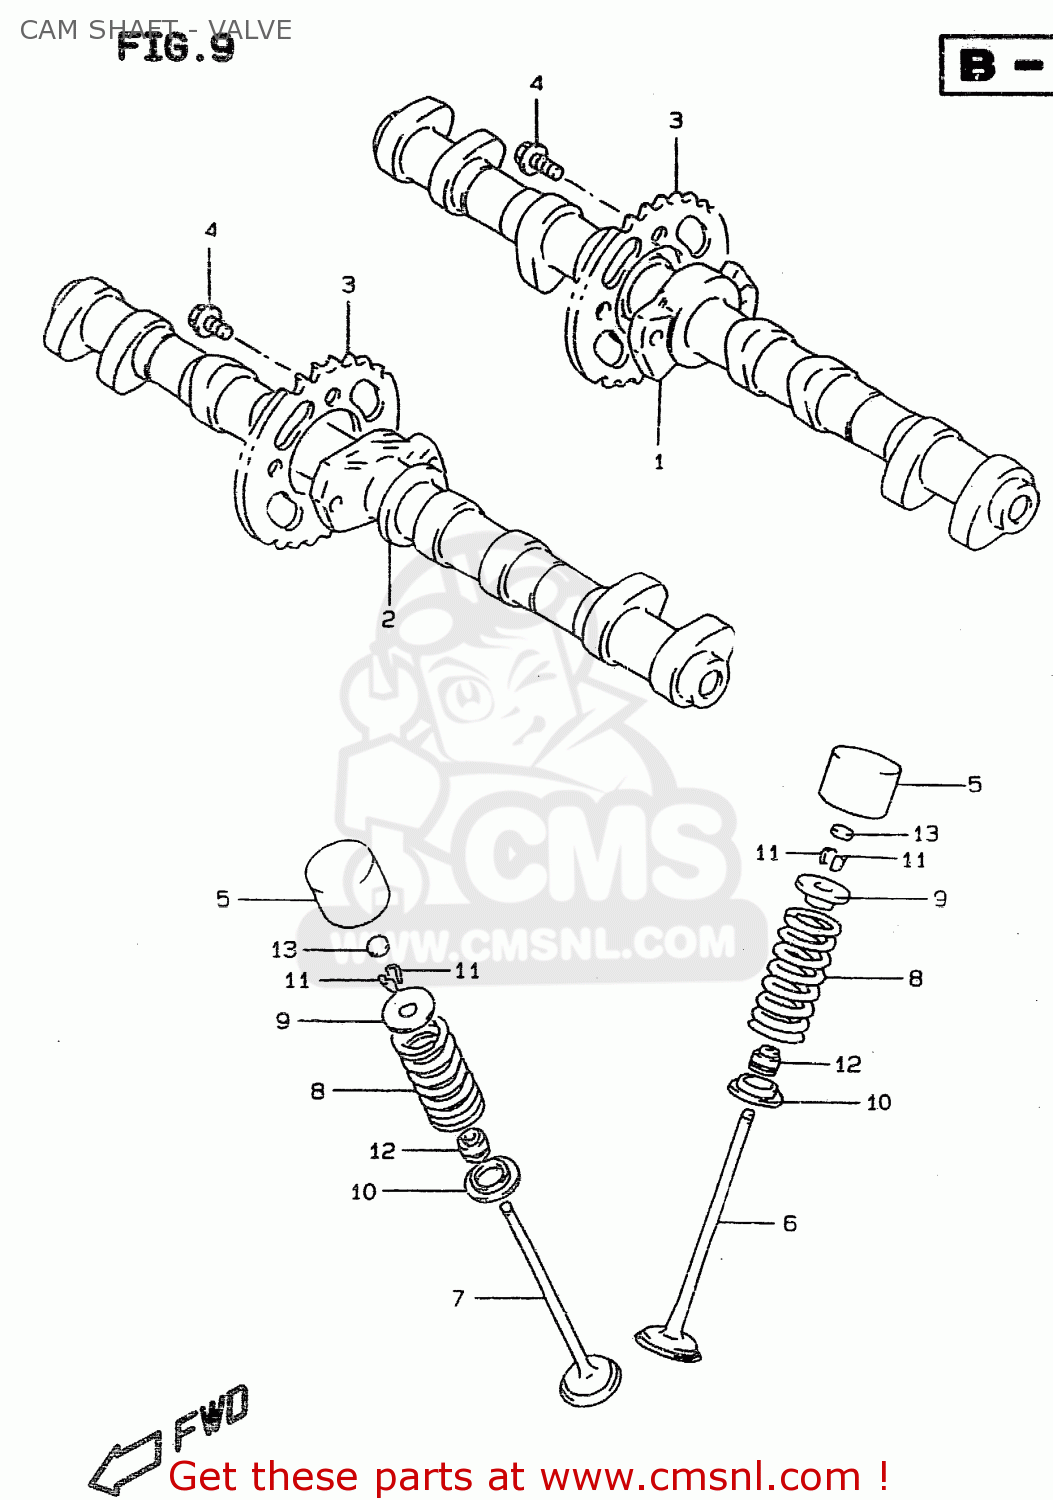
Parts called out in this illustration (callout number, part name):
1	CAMSHAFT,INTAKE
2	CAMSHAFT,EXHAUST
3	SPROCKET,CAMSHAFT
4	BOLT(7X11)
5	TAPPET
6	VALVE,INTAKE
7	VALVE,EXHAUST
8	SPRING,VALVE
9	RETAINER,VALVE SPRING
10	SEAT,VALVE SPRING
11	COTTER VALVE
12	SEAL,OIL(4.5X10X8)
13	SHIM,TAPPET
15	CASE,TAPPET SHIM
